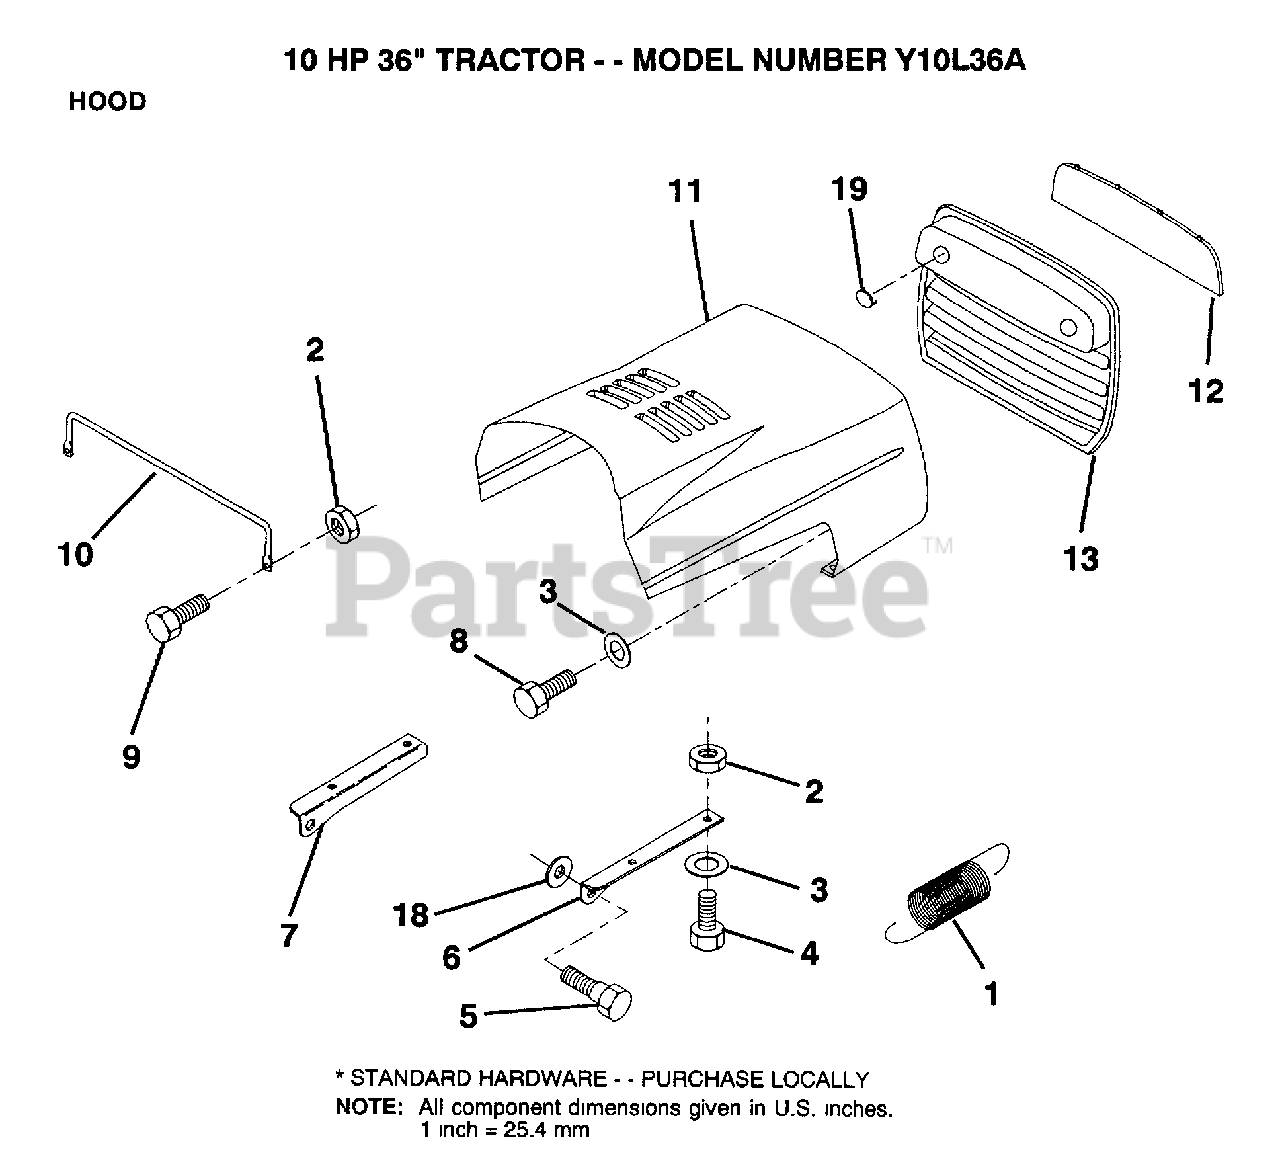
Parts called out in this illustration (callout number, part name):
1	EXT SPRING
2	NUT
3	WASHER
4	BOLT
6	BRKT HOOD RH
7	BRKT HOOD LH
10	"BRACE,HOOD"
11	HOOD
12	LENS
13	GRILL
18	WASHER
